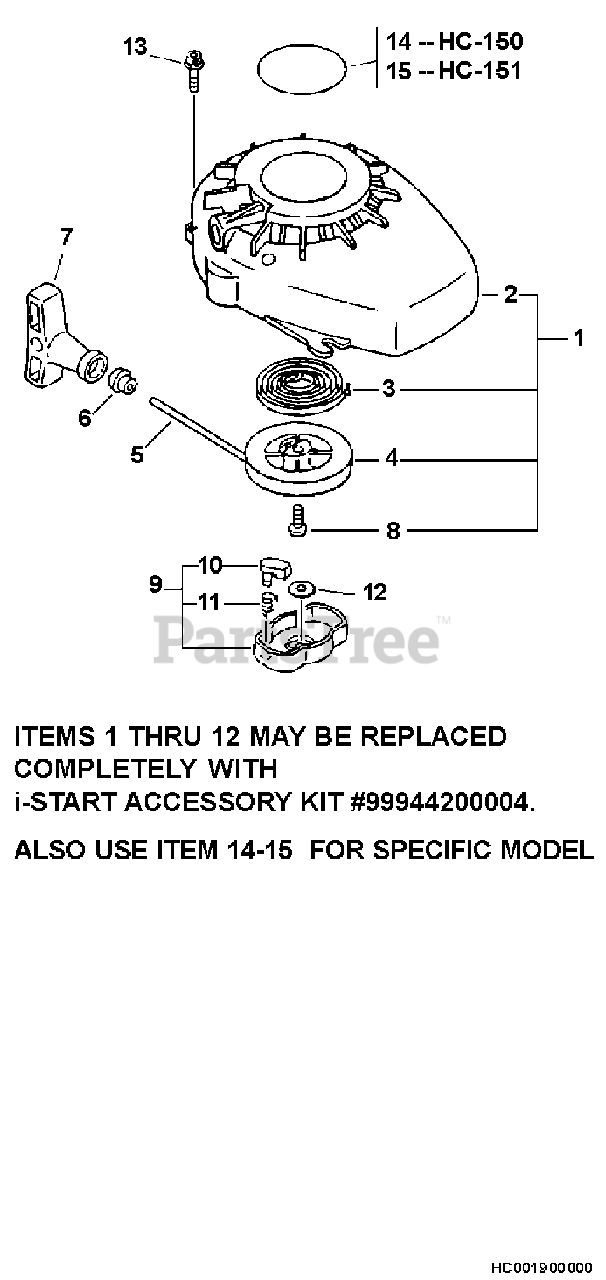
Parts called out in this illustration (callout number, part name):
1	STARTER ASSY
2	CASE, FAN
3	SPRING, REWIND
4	REEL, ROPE
5	ROPE, STARTER - 3X1000
6	GUIDE, ROPE
7	GRIP, STARTER
9	STARTER PAWL ASSY
10	PAWL, STARTER - BLACK
11	SPRING, RETURN
12	LOCKWASHER - 8
13	SCREW - 4X16
14	LABEL - MODEL HC-150
15	LABEL - MODEL HC-151
